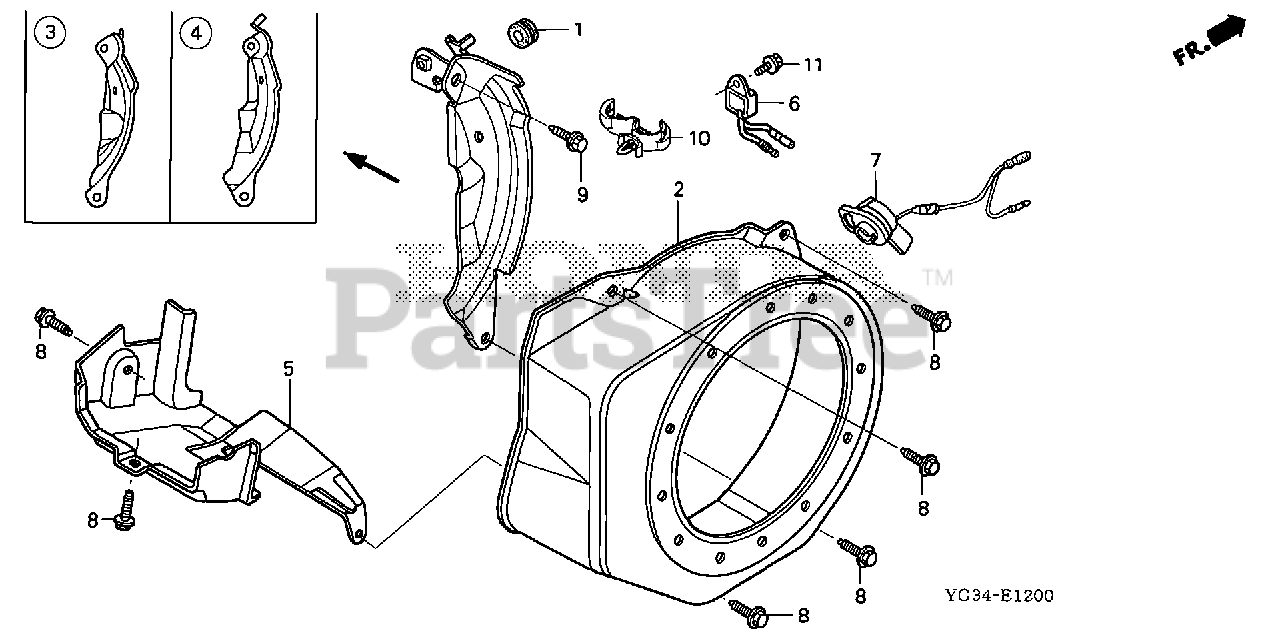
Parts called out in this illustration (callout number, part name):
2	COVER, FAN *R280* (POWER RED)
4	PLATE, SIDE (OIL ALERT)
5	SHROUD
6	ALERT UNIT, OIL
7	SWITCH ASSY., ENGINE STOP (TOYO DENSO)
7	SWITCH ASSY., ENGINE STOP
8	BOLT, FLANGE (6X12) (CT200)
9	BOLT, FLANGE (6X20) (CT200)
10	CLIP, HARNESS
11	BOLT, FLANGE (6X8)
